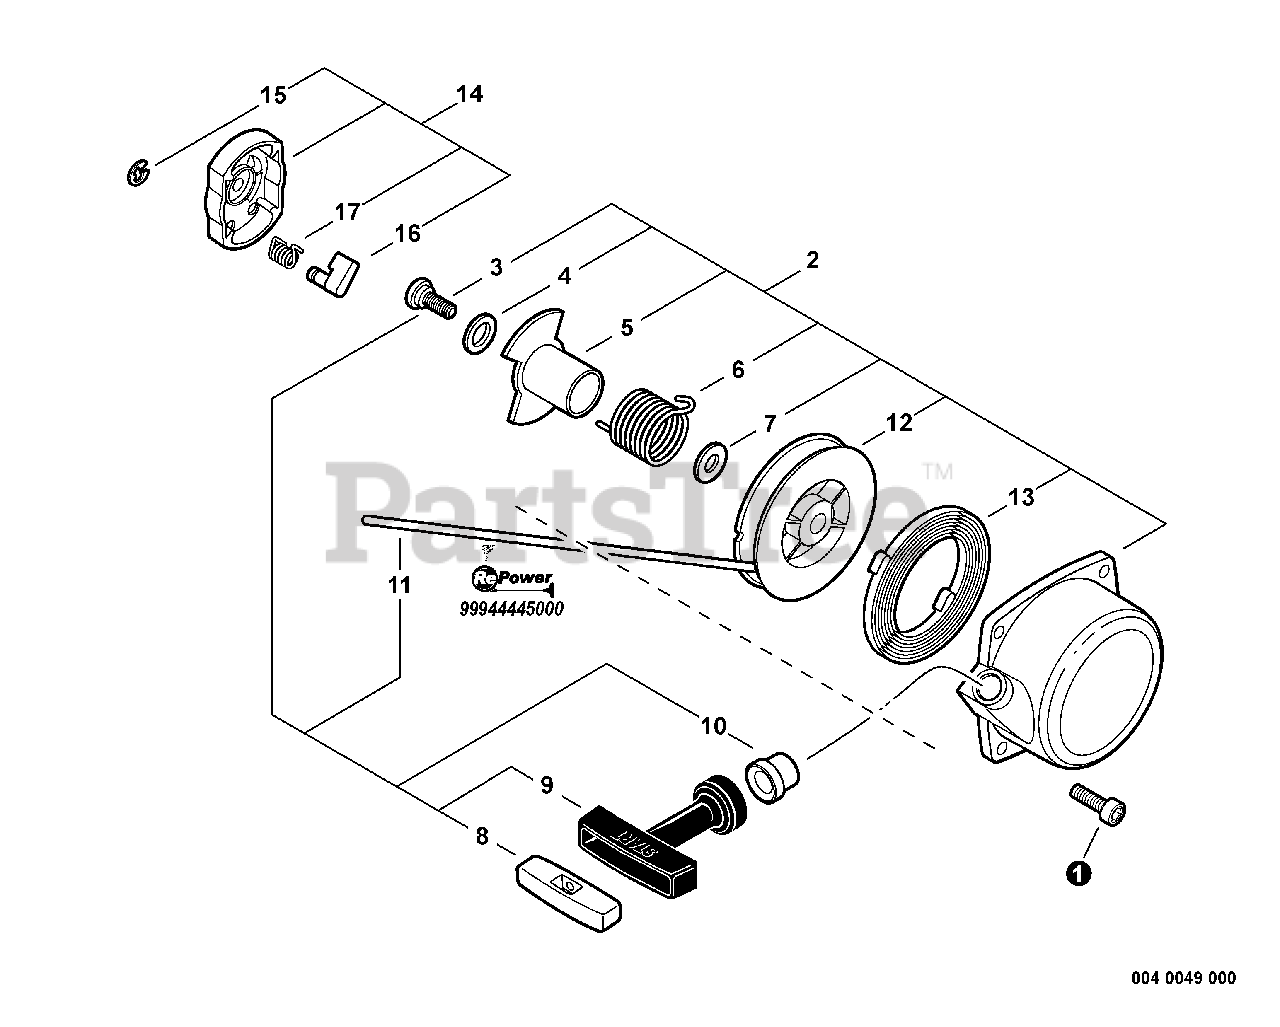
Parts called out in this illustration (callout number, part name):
1	BOLT, TORX 5×16
2	STARTER ASSY, RECOIL
3	SCREW
4	WASHER, THRUST
5	PAWL CATCHER
8	RETAINER, ROPE
9	GRIP, STARTER
10	GUIDE, ROPE
11	ROPE, STARTER 3.5×1000 MM
12	REEL, ROPE
13	SPRING, RECOIL
14	PULLEY ASSY, STARTER
15	E-RING 4
16	PAWL, STARTER
17	SPRING, RETURN
180	BULK STARTER ROPE - Ø 3.5 MM×61 M
